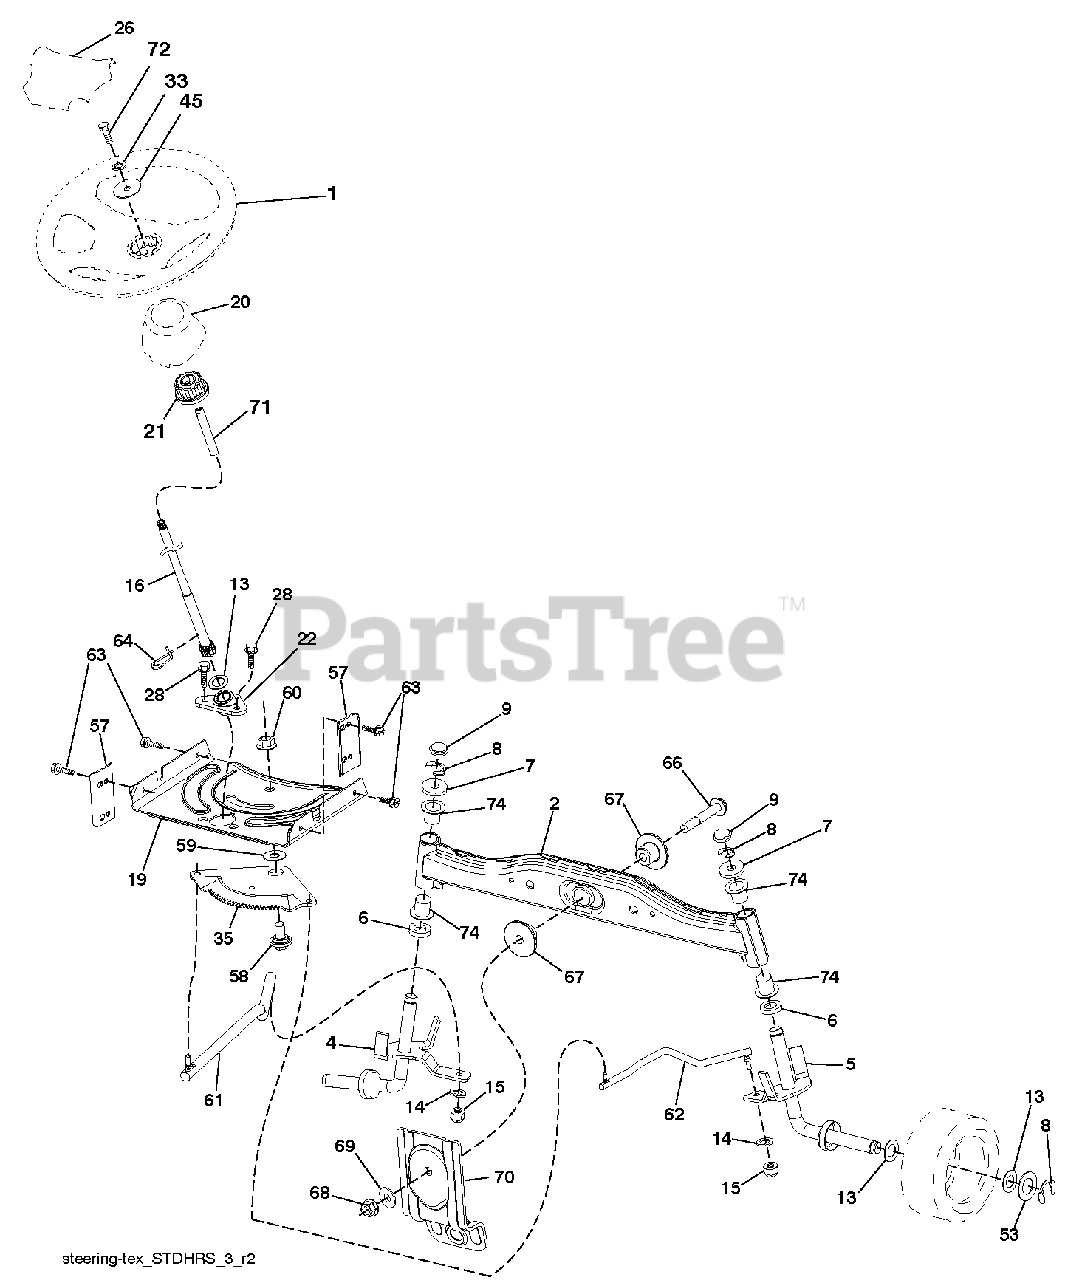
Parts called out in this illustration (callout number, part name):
1	Wheel, Steering
2	Axle Asm., Front
4	Spindle Asm., LH
5	Spindle Asm., RH
6	Washer Thrust 0.75 x 1.23
7	Washer 25/32 x 1-5/8 x 16 Ga.
8	Ring, Clip #T5304-75
9	Cap, Spindle
13	Washer 25/32 x 1-1/4 x 16 Ga.
14	Washer Lock 3/8
15	Nut, Crown Lock 3/8-24 unf
16	Shaft Steering
19	Plate Steering
20	Boot, Steering
21	Adapter, Wheel Steering
22	Supt. Strg. Lower
26	Insert, Wheel Steering
28	Screw 3/8-16 x 3/4
33	Washer Lock 5/16
35	Gear, Sector Plate
45	Washer 11/32 x 2-3/8 x 12 Ga.
53	Washer Hardened .793 x 1.637 x .060
57	Bracket Upstop
58	Bolt Shoulder Sector Pivot CFM
59	Washer Thrust Sector Steering
60	Nut Flange Lock 5/8-11
61	Draglink, LH
62	Draglink, RH
63	Screw 5/16-18 x 3/4
64	Retainer Clip Spring Steering
66	Bolt Hex Fghd 7/16-14 x 3 Serr
67	Bushing PM Front Axle
68	Nut Lock Flange 7/16-14 Gr. 5
69	Washer 1.5 x .505 x .118
70	Bracket Deck Susp. Front
71	Shaft Ext. Steering
72	Bolt 5/16-18 x 4 w/Patch
74	Bearing Col. Strg.
